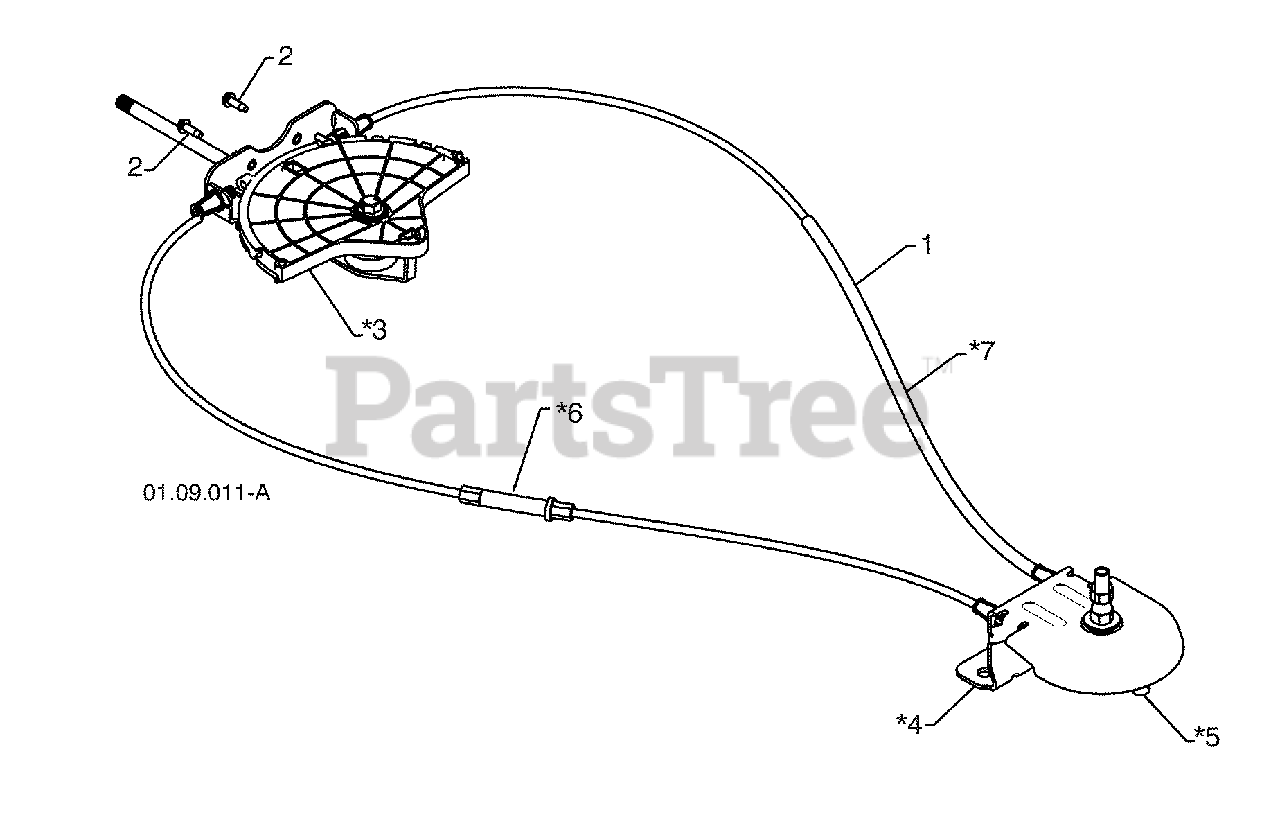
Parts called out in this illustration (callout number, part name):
1	LEVER/CABLE ROTATOR ASSEMBLY
2	SCREW 10-24 X .625
3	ROTATOR HEAD
4	ROTATOR PIVOT BRACKET
5	PULLEY PIVOT
6	CABLE ASSEMBLY ADJUSTABLE GRAY
7	CABLE ASSEMBLY HEAT SHIELD GRAY
